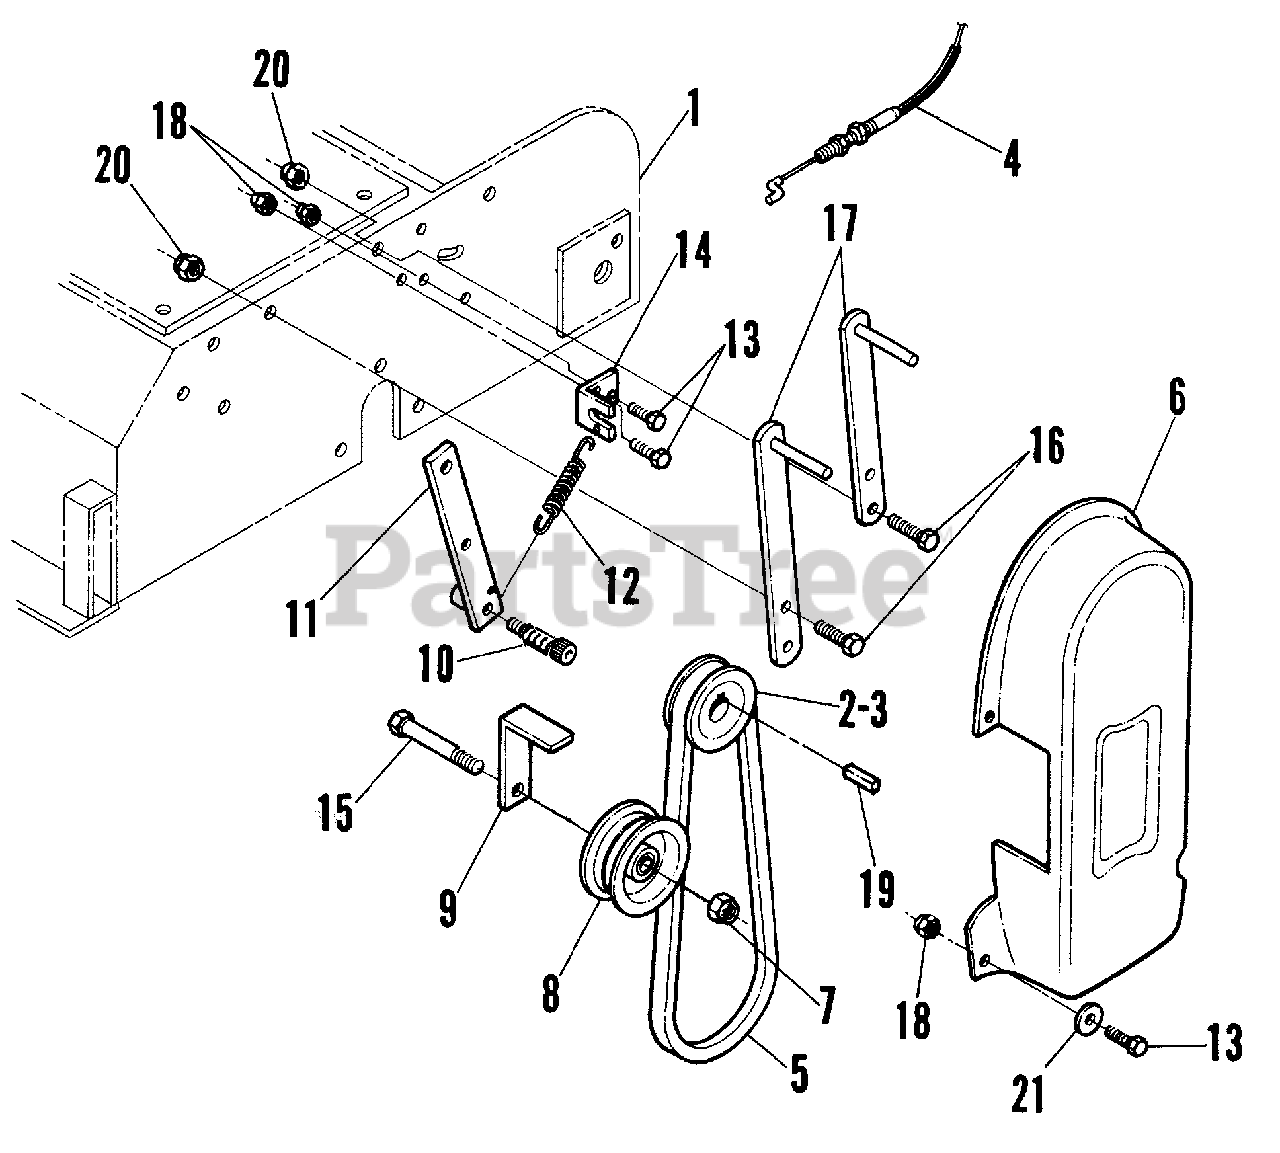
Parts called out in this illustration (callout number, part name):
1	BODY w/Decals
2	DRIVE PULLEY w/Set Screws
3	SET SCREW, 5/16-18 x 3/8" Knurled Point
4	CABLE, Drive
5	DRIVE BELT
6	SHIELD, Belt
7	NUT, 3/8-16 Hex Nyloc
8	PULLEY, Idler
9	BELT SNUBBER
10	SHOULDER BOLT, Socket Head
11	IDLER ARM
12	IDLER SPRING
13	SCREW, 1/4-20 x 5/8" Hex Head Cap, Grade 5
14	BRACKET
15	SCREW, 3/8-16 x 2" Hex Head Cap, Grade 5
16	SCREW, 5/16-18 x 3/4" Hex Head Cap, Grade 2
17	BELT GUIDE
18	NUT, 1/4-20 Hex Nyloc
19	MACHINE KEY, 3/16" Square x 1-3/4"
20	NUT, 5/16-18 Hex Nyloc
21	WASHER, 1/4" Flat
